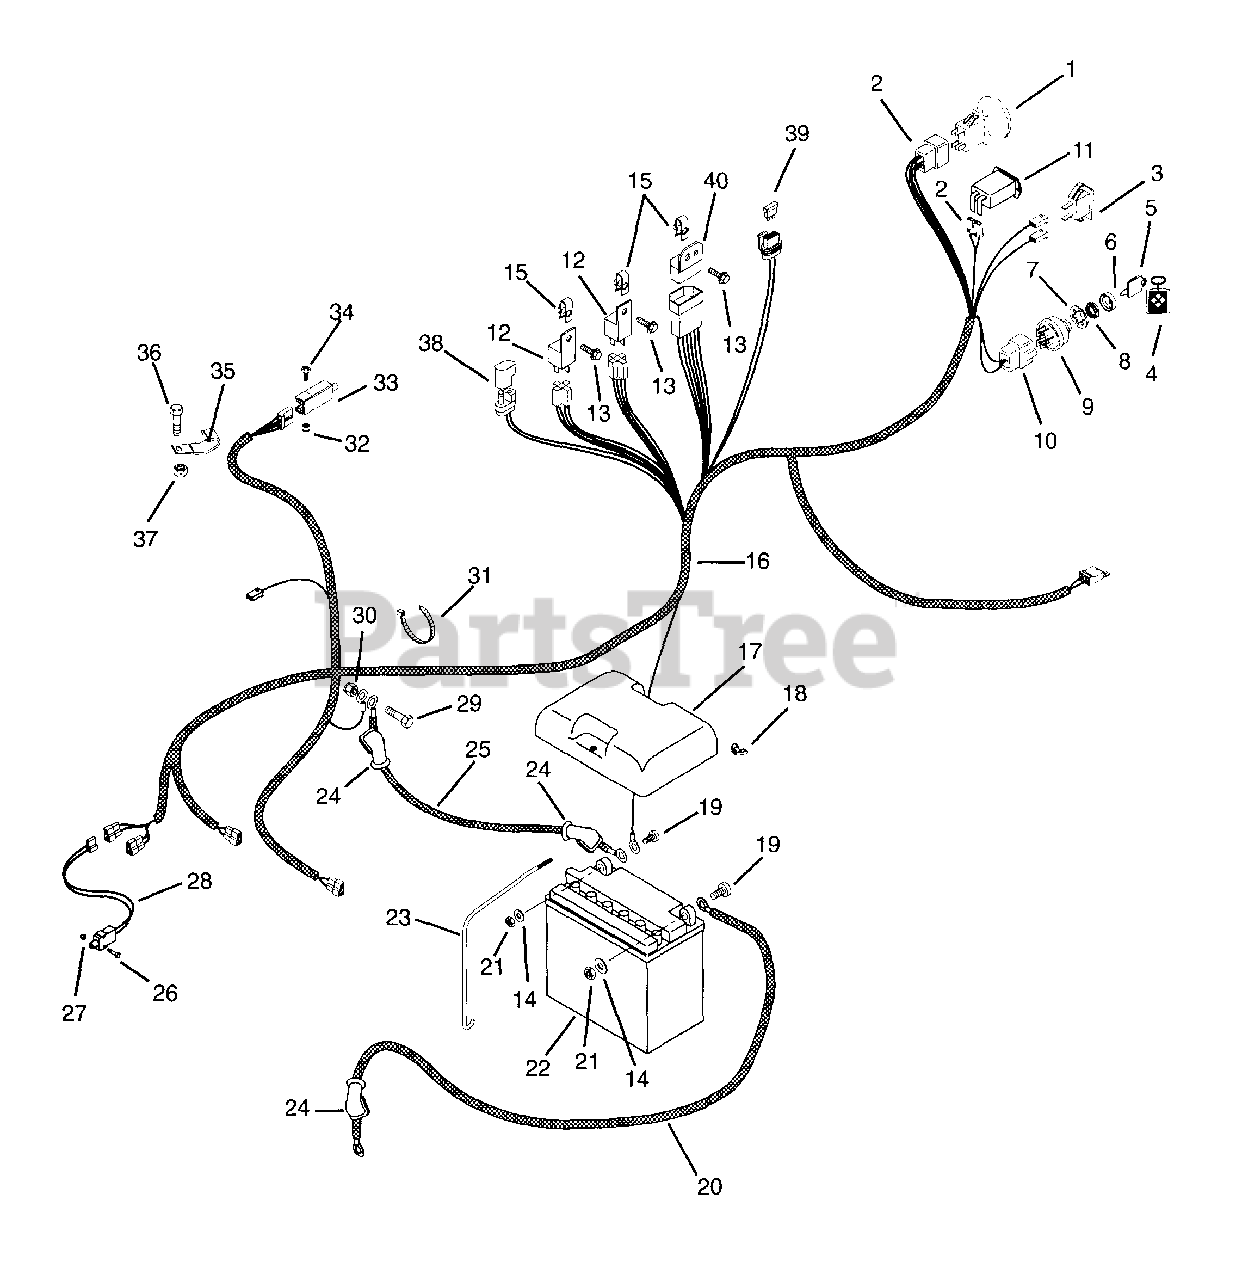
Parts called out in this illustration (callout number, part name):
1	Switch-Clutch with Retainer Ring
2	Terminal
3	Light-Indicator
4	Key Chain
5	Ignition Switch Key
6	Cap-Ignition Switch
7	Nut-Panel .562-24
8	Washer-Lock-Internal .563 x .040
9	Key Switch
10	Connector
11	Hour Meter
12	Relay
13	Screw-Machine 10-24 x .75 Hex Washer Head
14	Washer-Flat-Steel .281 x .620 x .065
15	Retainer Nut 10-24
16	Harness-Wiring
17	Cover-Battery
18	Nut-Locking-Wing .250-20
19	Bolt-Hex .25-20 x .75 Grade 5
20	Cable-Starter
21	Nut-Hex .25-20
23	Rod-Battery
24	Boot-Insulator
25	Cable-Negative Battery
26	Screw-Machine 6-32 x .75
27	Nut-Locking-Nylon 6-32 w/Insert
28	Switch
29	Bolt-Hex .31-18 x 1.00 Grade 5
30	Nut-Locking-Center .31-18
31	Tie-Wrap-Black
32	Nut-Locking-Nylon 10-24 w/Insert
33	Switch-Single Pole N.O.
34	Screw-Machine .38-7.0
36	Bolt-Hex .38-16 x 1.00 Grade 5
37	Nut-Locking-Center .38-16
38	Molded Diode Plug
39	Fuse, 30 Amp
40	Module, Time Delay
